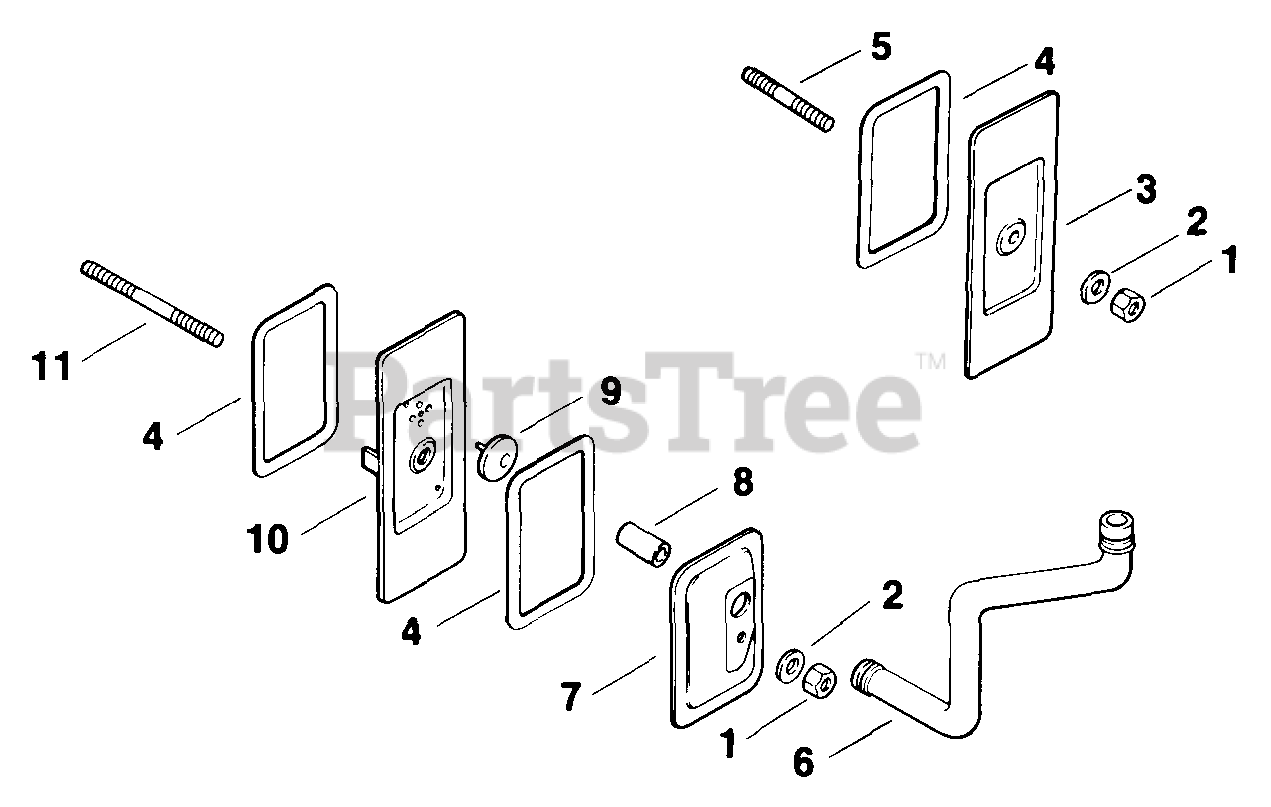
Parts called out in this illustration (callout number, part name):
1	Nut, Hex. 1/4-20
2	Washer, Plain 1/4"
3	Cover, #2 Cylinder Valve
4	Gasket, Cover
5	Stud, #2 Cylinder Valve Cover 1/4-20x2-1/4"
6	Hose, Breather
7	Cover, #1 Upper Cylinder Valve
8	Seal, Breather
9	Valve, Umbrella
10	Cover, #1 Lower Cylinder Valve
11	Stud, #1 Cylinder Valve Cover 1/4-20x3-1/4"
